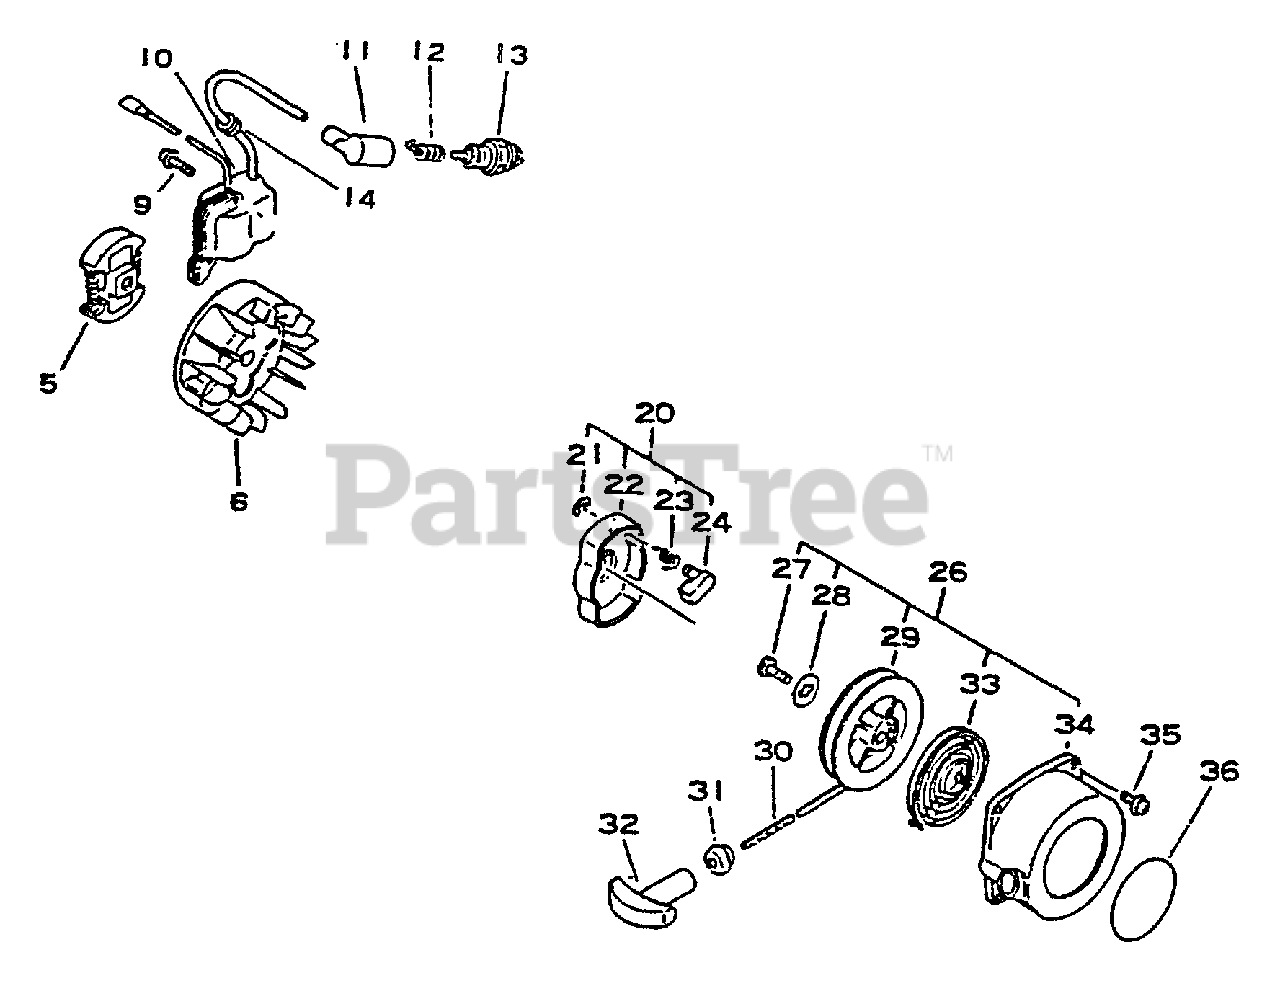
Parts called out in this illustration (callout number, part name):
5	CLUTCH ASSY
6	FLYWHEEL
9	SCREW - 4X22
10	COIL, IGNITION
11	CAP, SPARK PLUG
12	TERMINAL, SPARK PLUG CAP
13	SPARK PLUG -- CJ-7Y
14	GROMMET
20	STARTER PAWL ASSY
21	RING, RETAINING - 4
22	CATCHER, PAWL
23	SPRING, RETURN
24	PAWL, STARTER
26	STARTER ASSY
28	WASHER
29	REEL, ROPE
30	ROPE, STARTER - 3X890
31	GUIDE, ROPE
32	GRIP, STARTER
33	SPRING, REWIND
34	CASE, STARTER
35	SCREW - 4X16
36	LABEL - ECHO
